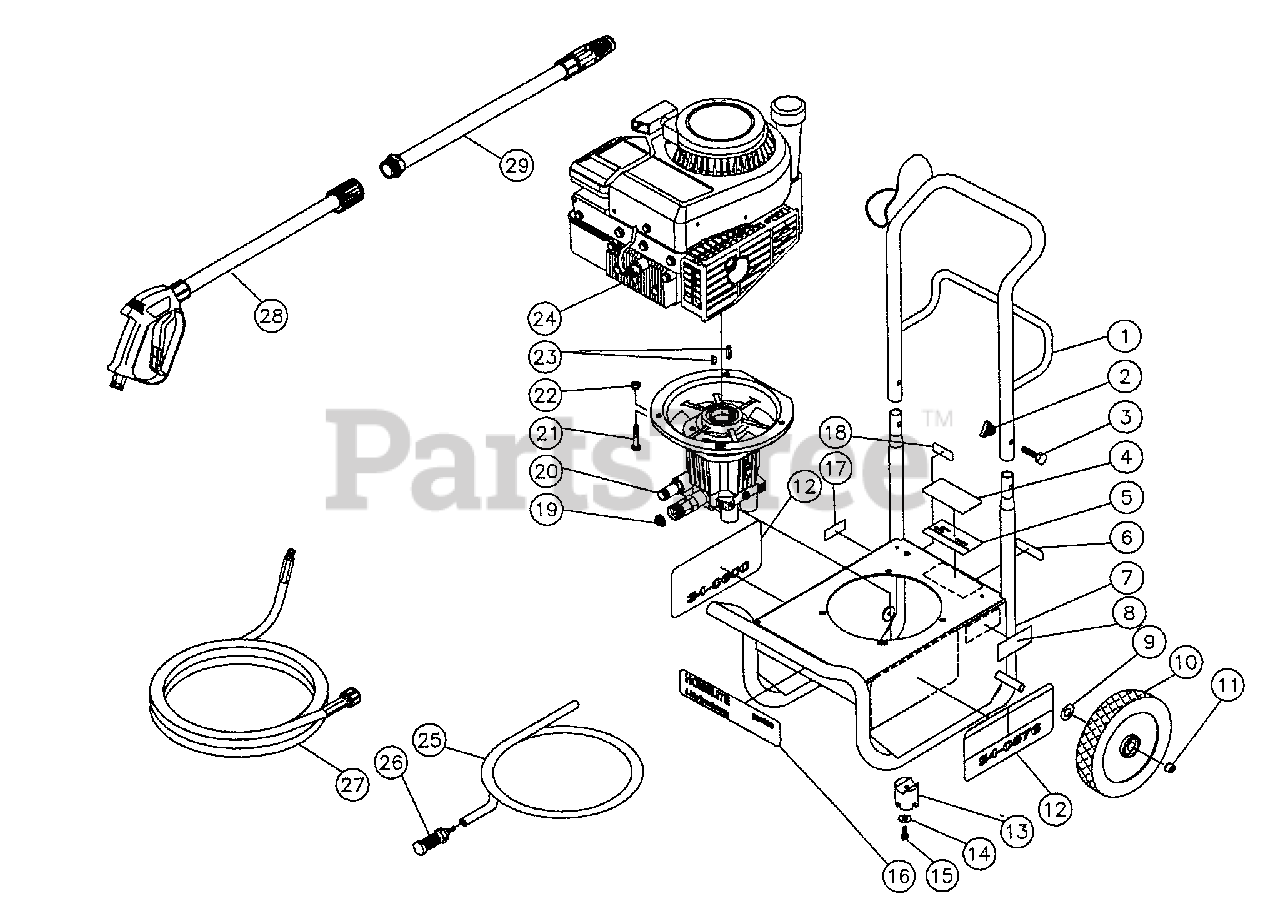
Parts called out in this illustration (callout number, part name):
4	Decal-Clear Laminate
5	Decal-Silver Sticker
6	Decal-Serial Number
8	Decal-Warning: Muffler Hot
12	Decal-Warn/Caution/Operate English
13	Isolator
16	Decal-1500 PSI
17	Decal-Caution: Allow to Cool
18	Decal-Adjustable Pressure
23	Key-Woodruff
24	Engine-3.75 HP Briggs & Stratton
25	Detergent Hose
26	Detergent Strainer
27	Pressure Hose
28	Gun Assembly
29	Variable Nozzle Assembly 1.2mm
